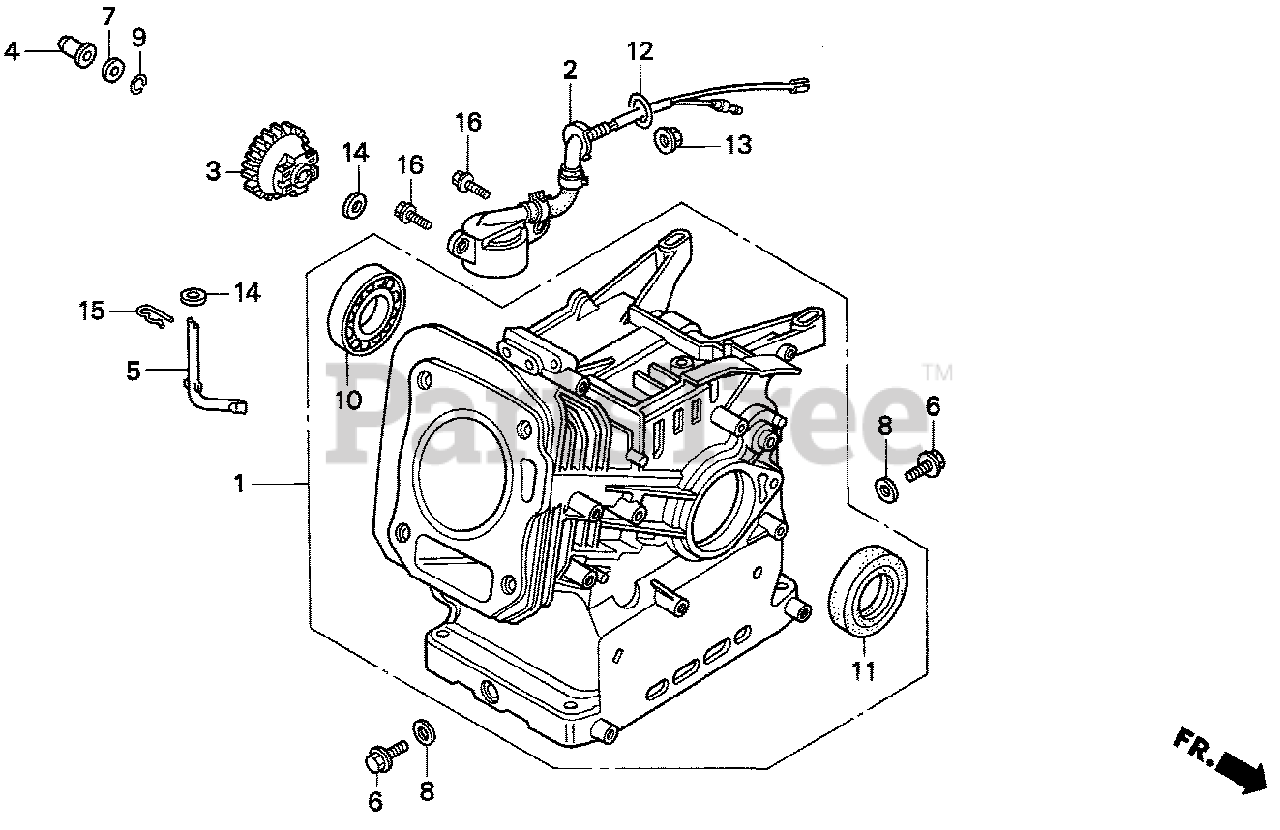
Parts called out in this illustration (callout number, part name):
1	CYLINDER ASSY. (OIL ALERT)
1	CYLINDER ASSY.
2	SWITCH ASSY., OIL LEVEL
3	GOVERNOR ASSY.
4	SLIDER, GOVERNOR
5	SHAFT, GOVERNOR ARM
6	BOLT, DRAIN PLUG
7	WASHER, THRUST (6MM)
8	WASHER, DRAIN PLUG (10.2MM)
9	CLIP, GOVERNOR HOLDER
10	BEARING, RADIAL BALL (6205)
11	OIL SEAL (25X41X6)
12	O-RING (13.5X1.5) (ARAI)
13	NUT, FLANGE (10MM)
14	WASHER, PLAIN (6MM)
15	PIN, LOCK (8MM)
16	BOLT, FLANGE (6X12)
